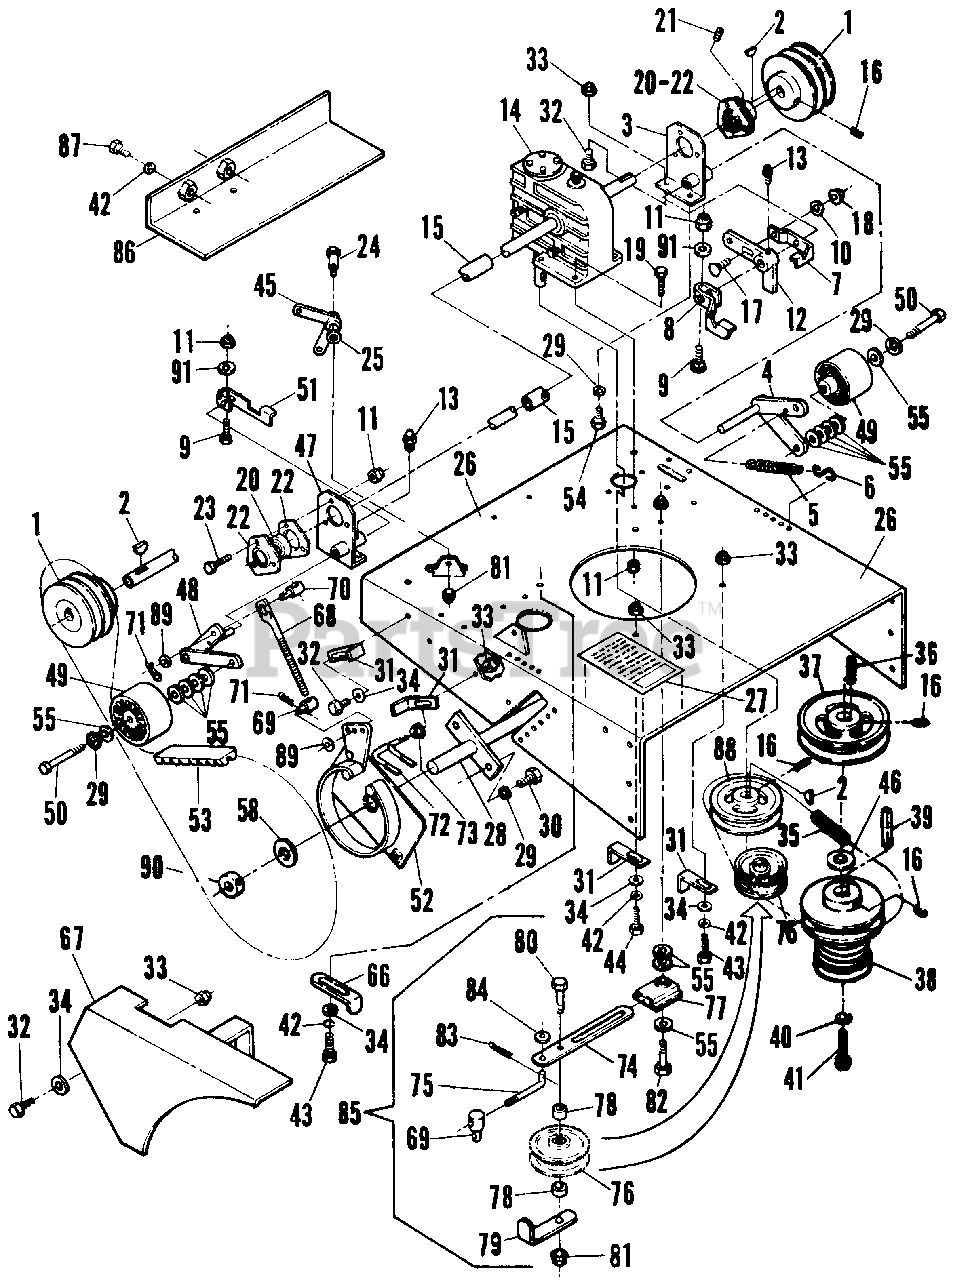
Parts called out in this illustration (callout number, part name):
1	PULLEY, Output w/Set Screw
2	KEY, Woodruff No. 605
3	BRK'T, Bearing Support Weldment
4	BELLCRANK, Traction Weldment
5	SPRING, Extension
6	HOOK, Spring(s)
7	TAB, Blade Switch
8	TAB, Traction Switch Left
9	BOLT, Carriage 1/4-20 x 1 1/4
10	WASHER, 1/4 SAE Flat
11	NUT, Nyloc Hex 1/4-20
12	BELLCRANK, Blade Control
13	FITTING, Zerk 1/4-20
14	BOX, Worm Gear Reduction
15	TUBE, Transmission Output Shaft
16	SCREW, Set 5/16 - 18 x 3/8
17	BOLT, Carriage 1/4 - 20 x 3/4
18	NUT, Hex Flange Lock 1/4-20
19	SCREW, Hex Head Cap 1/4 - 20 x 1
20	BEARING, Flange w/Set Screws
21	SCREW, Set Nyloc 10-32 x 1/4
22	PLATE, Flange
23	SCREW, Hex Head Cap 1/4-20 x 5/8
24	SHOULDER BOLT
25	MACHINERY BUSHING 1/2
26	REAR DECK w/Decal
27	DECAL, Caution
28	AXLE, Weldment
29	WASHER, Lock 3/8
30	SCREW, Hex Head Cap 3/8 -16 x 1
31	GUIDE, Belt
32	SCREW, Hex Head Cap 5/16-18 x 3/4
33	NUT, Nyloc Hex 5/16-18
34	WASHER, Flat 5/16
35	BELT, Variable Speed
36	KEY, Square 1/4 x 1 3/4
37	PULLEY, w/Set Screws
38	PULLEY, Variable Speed
39	SQUARE KEY 1/4 x 11/16
40	WASHER, Lock 7/16
41	SCREW, Hex Head Cap 7/16-20 x 2 1/4
42	WASHER, Lock 5/16
43	SCREW, Hex Head Cap 5/16 - 18 x 1 3/4
44	SCREW, Hex Head Cap 5/16-18 x 2 1/4"
45	BELLCRANK WELDMENT
46	MACHINERY BUSHING 1"
47	BRK'T, Bearing Support
48	BELLCRANK, Traction Right
49	PULLEY, Idler
50	SCREW, Hex Head 3/8 - 24 x 1 3/4
51	TAB, Traction Switch
52	BRAKE ASS'Y, Right
53	BELT, Traction
54	SCREW, Hex Head Cap 3/8" - 16 x 3/4"
55	WASHER, Flat 3/8 STD
58	MACHINERY BUSHING 7/8"
66	GUIDE, Belt (Rear)
67	FENDER, Right
68	LINKAGE, Brake
69	SWIVEL, Short
70	SWIVEL, Long
71	COTTER, #2 Hairpin
72	SCRAPER
73	NUT, 5/16 - 18 Whizlock
74	BAR, Slide
75	LINKAGE, Variable Speed Adjustment
76	PULLEY, Idler w/Bushing
77	BRACKET, Slide
78	SPACER (1" O.D. x 13/32 I.D. x 3/8)
79	GUIDE, Belt
80	SCREW, Hex Head Cap 3/8 - 16 x 2 1/2
81	NUT, Hex Flange 3/8 - 16
82	SCREW, Hex Head Cap 3/8 - 16 x 1 1/2
83	PIN, Cotter 3/32 x 1/2
84	WASHER, Flat 5/16 SAE
85	SLIDE, Variable Speed Assembly
86	SHIELD, Lower Belt
87	SCREW, Hex Head Cap 5/16 - 18 x 1
88	PULLEY, Transmission w/Set Screws
89	WASHER, Brake Linkage
90	COLLAR, Clamp w/Set Screw 7/8
91	WASHER, 1/4 "D"
